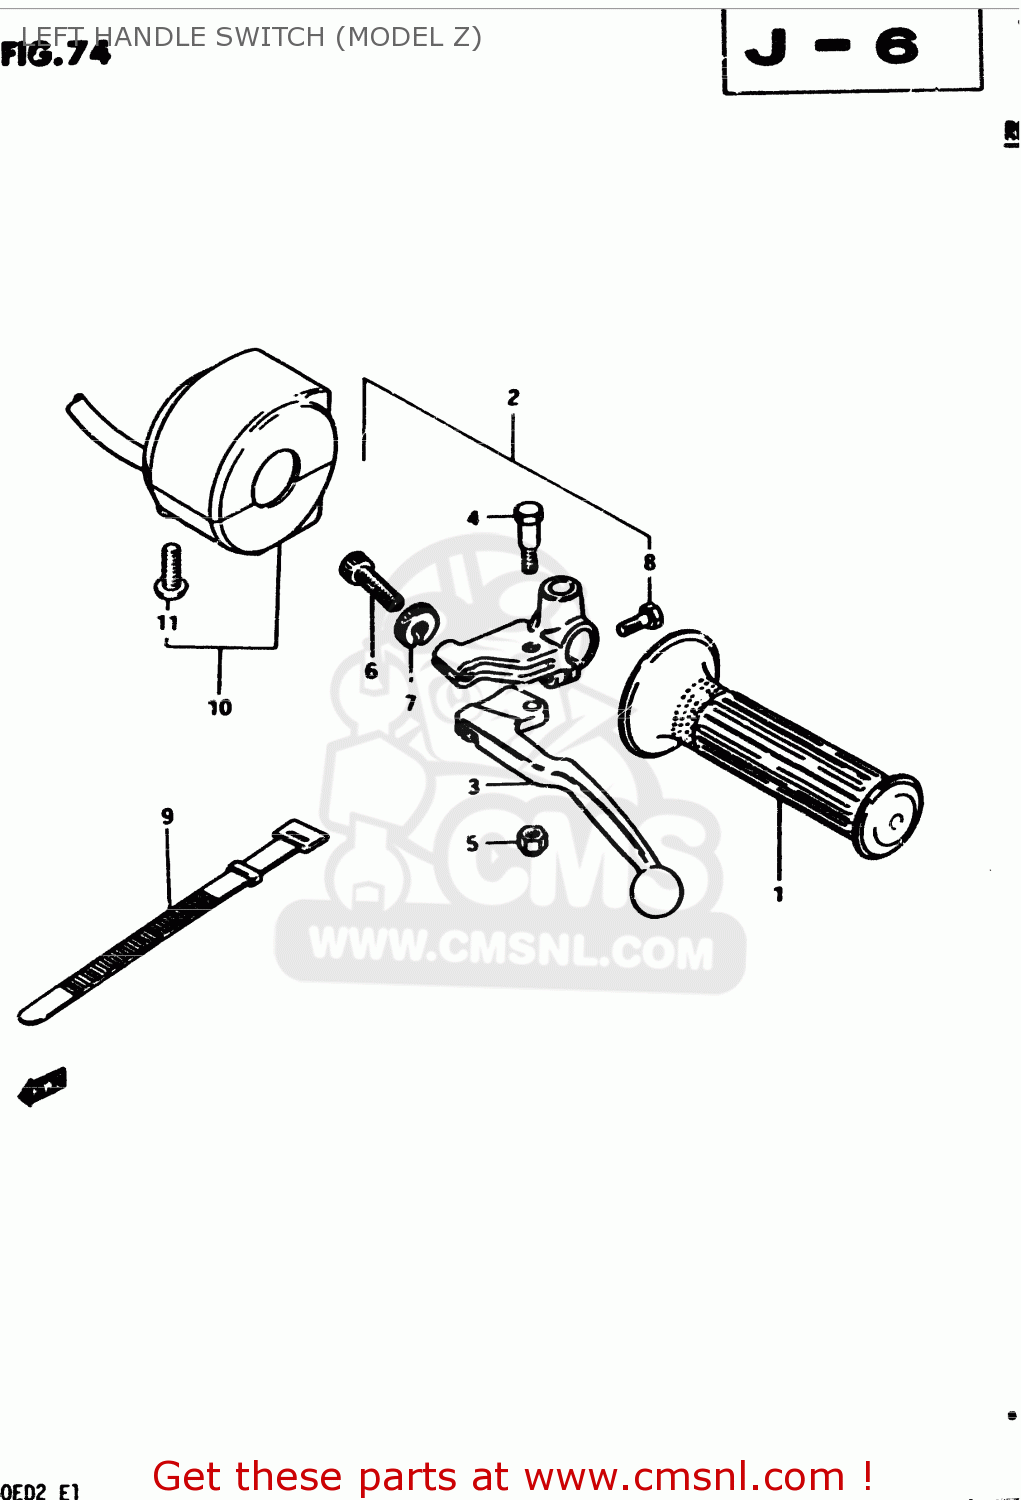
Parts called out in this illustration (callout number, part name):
1	GRIP,LEFT
2	LEVER ASSY, CLUTCH
3	LEVER,CLUTCH
4	BOLT,LEVER
5	NUT 6MM
6	ADJUSTER,CABLE
7	NUT,CABLE ADJUSTER LOCK
8	BOLT
9	CLAMP(L:120)
10	SWITCH ASSY, HANDLE LH
11	SCREW
